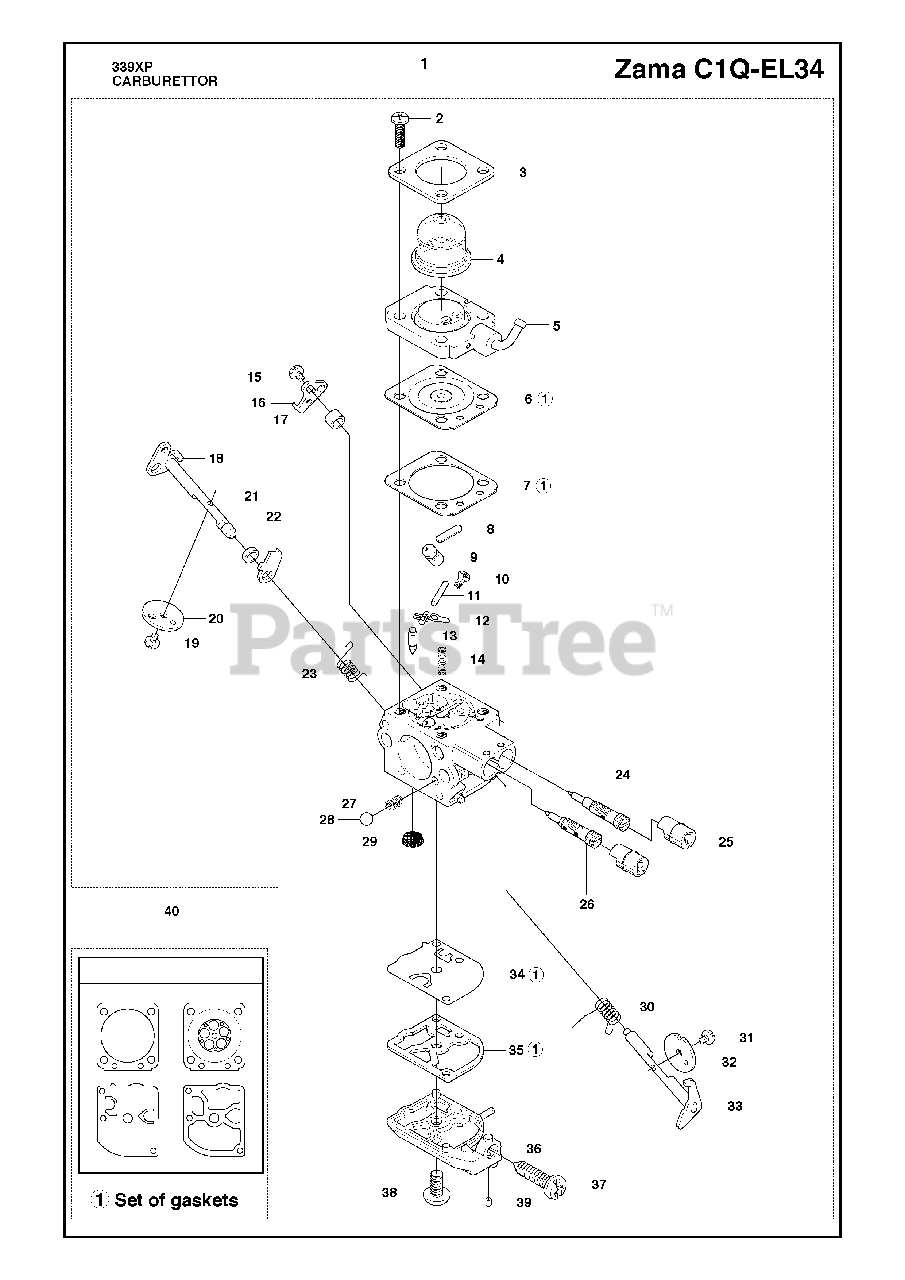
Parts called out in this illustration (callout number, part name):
1	CARBURETOR
11	PIN FULCRUM
13	INLET NEEDLE
24	IDLE SCREW
25	LIMITER CAP KIT
26	SCREW
30	SPRING THROTTLE
32	THROTTLE FLAP
34	PUMP DIAPHRAGM
40	GASKET SET
